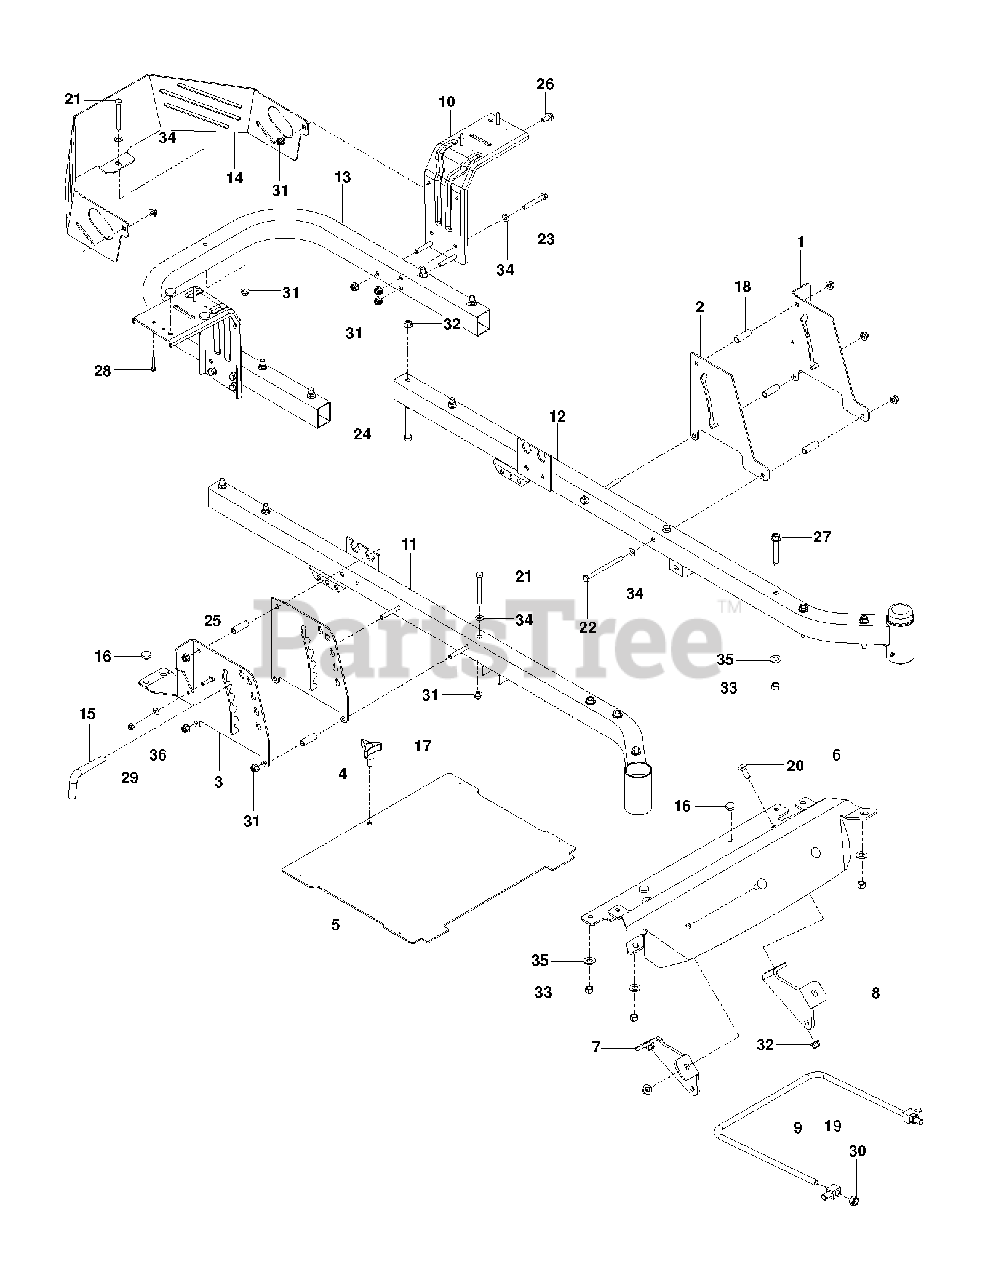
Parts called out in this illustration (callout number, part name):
1	PLATE, OUTER BRAKE, BLACK
2	PLATE, BRAKE LATCH, BLACK
3	PLATE.DECK HEIGHT.PNT.431.RZ
4	PLATE, DECK HEIGHT, BLACK
5	PLATE, FOOT W/DECALS RZ
6	FOOT.REST.MED.ORANGE
7	MOUNT, STRUT, RT, BLK
8	MOUNT, STRUT, LT, BLK
9	LINK, FRONT SUSP.
10	FENDER.SUPPORT.PNT.X431
11	FRAME, RT, ORANGE
12	FRAME, LT, ORANGE
13	FRAME TUBE, REAR ORG
14	GUARD REAR GREY
15	PIN.DECK.HEIGHT.RZ
16	GROMMET, BUMPER
17	KNOB W/STUD
18	SPACER.334.ID.5.OD.1.5.L
19	SWIVEL.TRUNION.LINK.DECK.FRONT
19	SCR #10-12X1-1/2HEX WASH HD ZD
21	BOLT HEX
23	BOLT.FIN HEX 5/16-18UNC X2 1/4
24	BOLT.HEX.FIN.3/8-16 X 3.GR5
25	BOLT
26	HHFS 5/16-18 X 3/4
27	HHFS 3/8-16 X 2-3/4 GR5 ZD
28	SCR #10-12X1-1/2HEX WASH HD ZD
29	LOCKNUT.NYLOC.1/4-20
30	7/16-14 HEX NUT W/NYL RING ZD
31	5/16-18 NYLOC FLANGE NUT
32	NUT 3/8-16 HEX FLG NYLOC ZD
33	NUT HEX 3/8-16 NYLON, THIN
34	WASHER
35	WASHER 3/8 FLAT
36	WASHER
